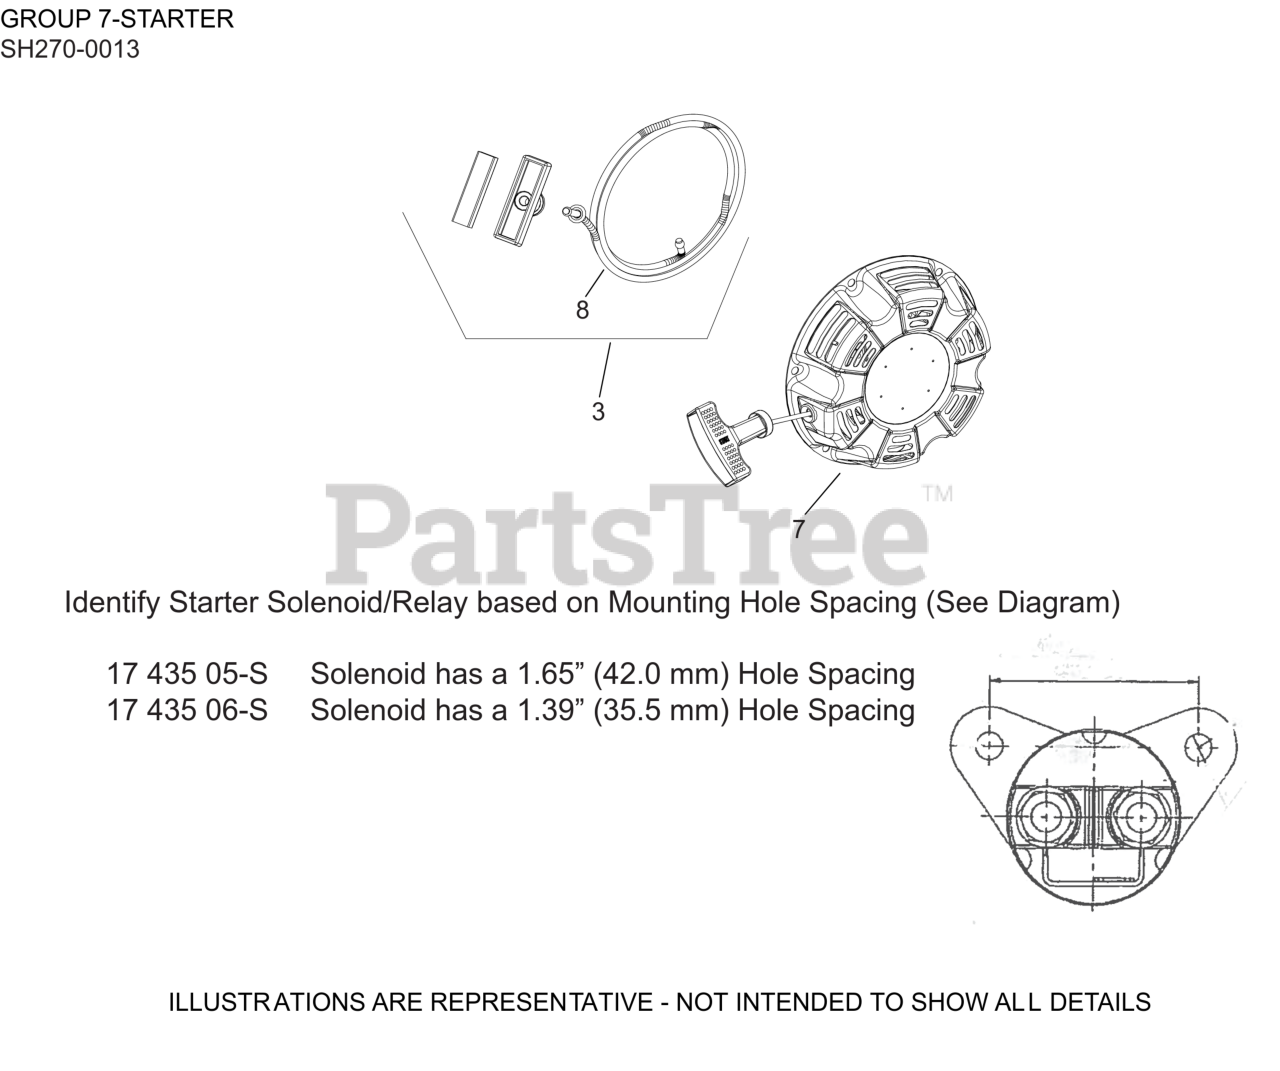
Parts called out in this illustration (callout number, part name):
3	KIT, STARTER ROPE W/HANDLE
7	RETRACTABLE STARTER ASSEMBLY
8	ROPE, STARTING
